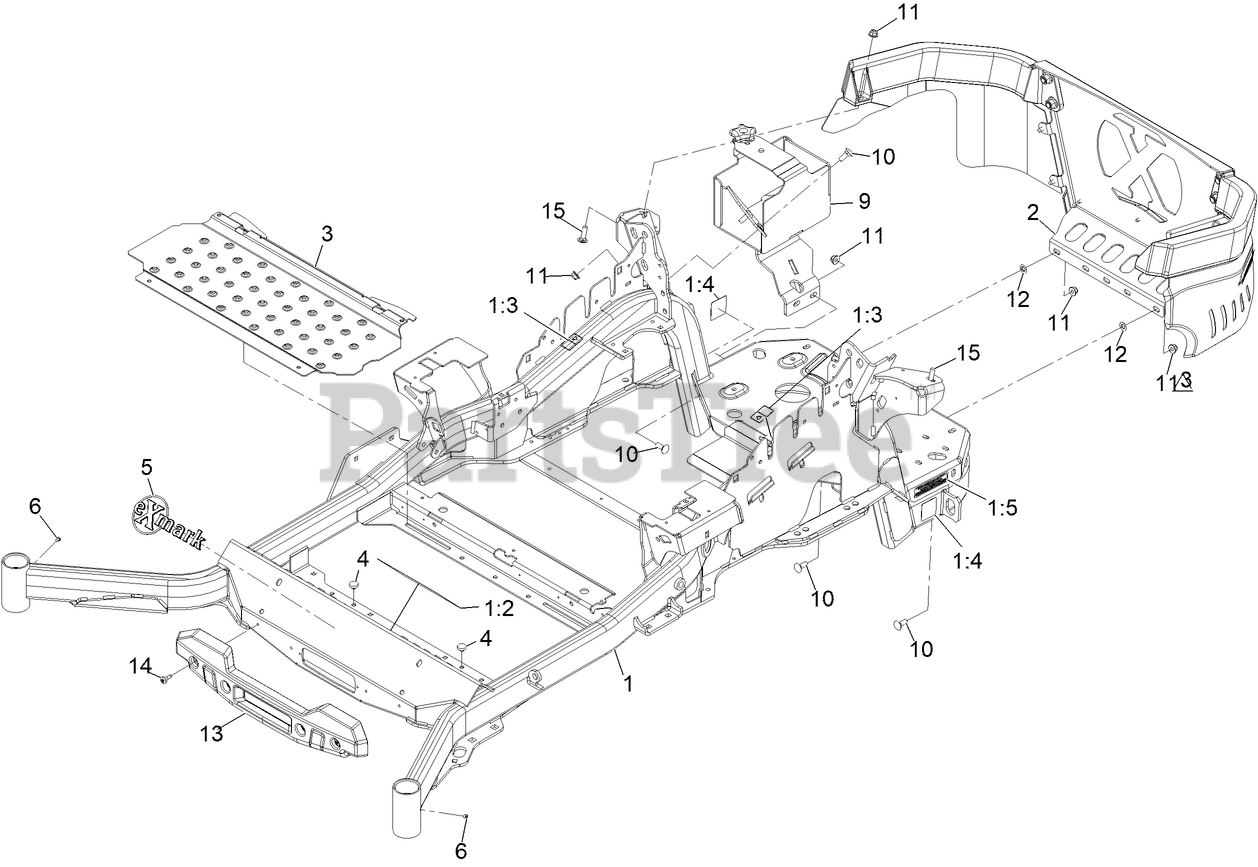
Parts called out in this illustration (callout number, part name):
1	ASM-Mainframe W/Decals
1:2	DECAL-DANGER
1:3	DECAL-WARNING
1:4	DECAL-HAZARD, PINCHED FINGER
1:5	DECAL-ARRESTOR, SPARK
2	Cage-Rear [oil Guard]
5	EMBLEM-EXMARK
9	ASM-Battery Box
10	BOLT-CARR
11	NUT-HF, NI
12	NUT-PUSH
13	BUMPER-FRONT
14	SCREW-SHOULDER
15	BOLT-CARR
